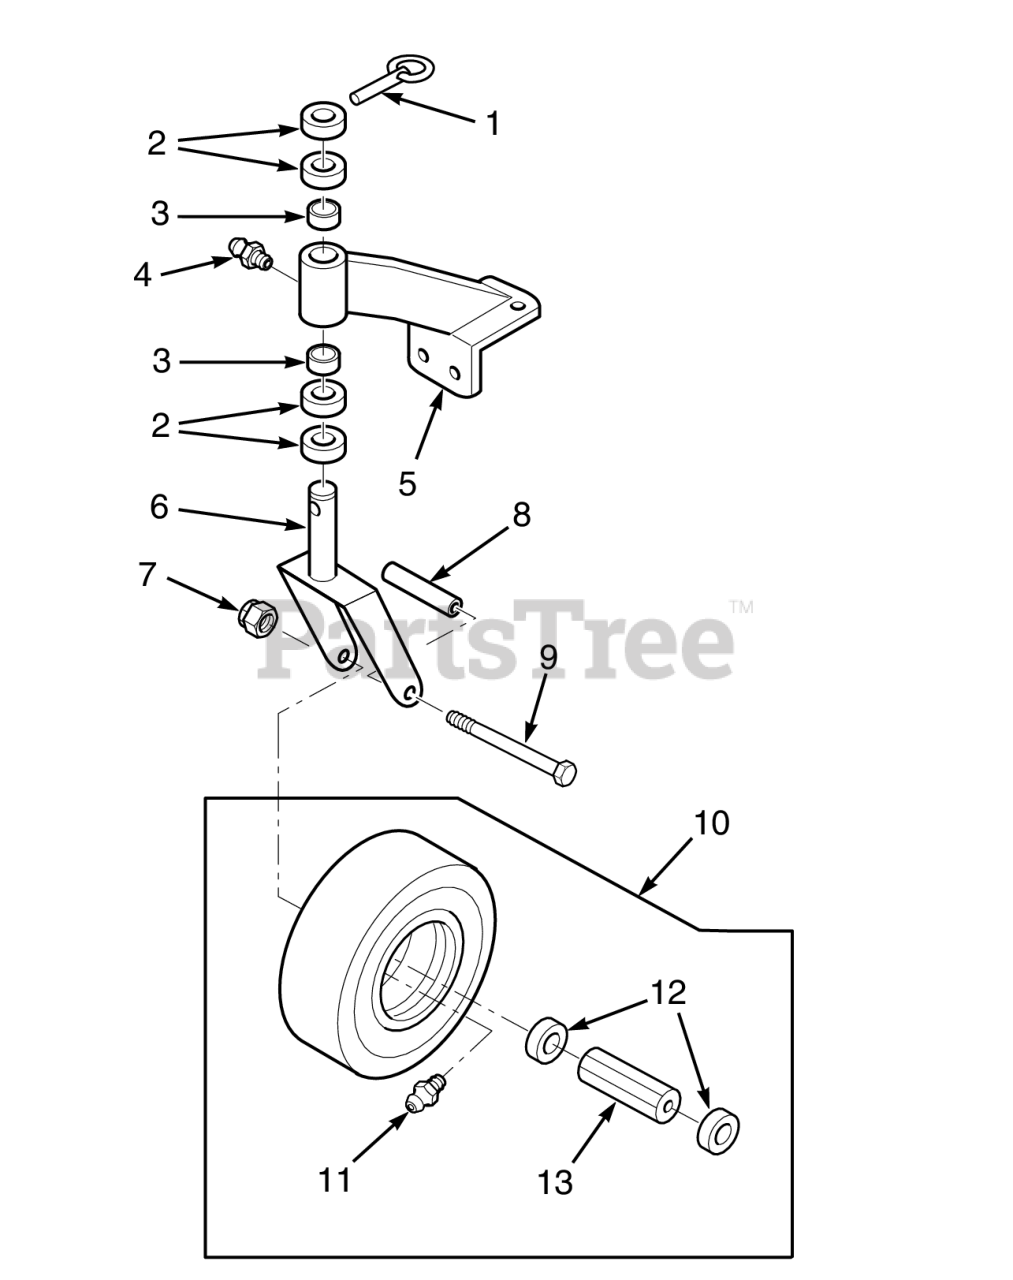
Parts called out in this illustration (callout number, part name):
1	Quick Pin, .438" Dia.
2	SPACER, CASTER YOKE, 1/2" THICK
3	Bronze Bushing, 7/8 ID x 1.0 Flanged
4	GREASE FITTING, STR. 1/4-28 SELF TAP.
5	SUPPORT ASSEMBLY(INCLUDES ITEMS 21, 82).
6	Caster Yoke Weldment
7	HEX LOCKNUT, ELASTIC STOP, 1/2-13
8	SLEEVE, CASTER WHEEL BEARING
9	Bolt, Hex Head 1/2-13 x 5-1/2" (Three Weights Installed)
10	Flat Free Tire Assy.
11	GREASE FITTING, 45 DEGREE 1/4-28
12	Retainer, Bearing, Caster Wheel
13	Roller Bearing, .625 x 3-1/4"
